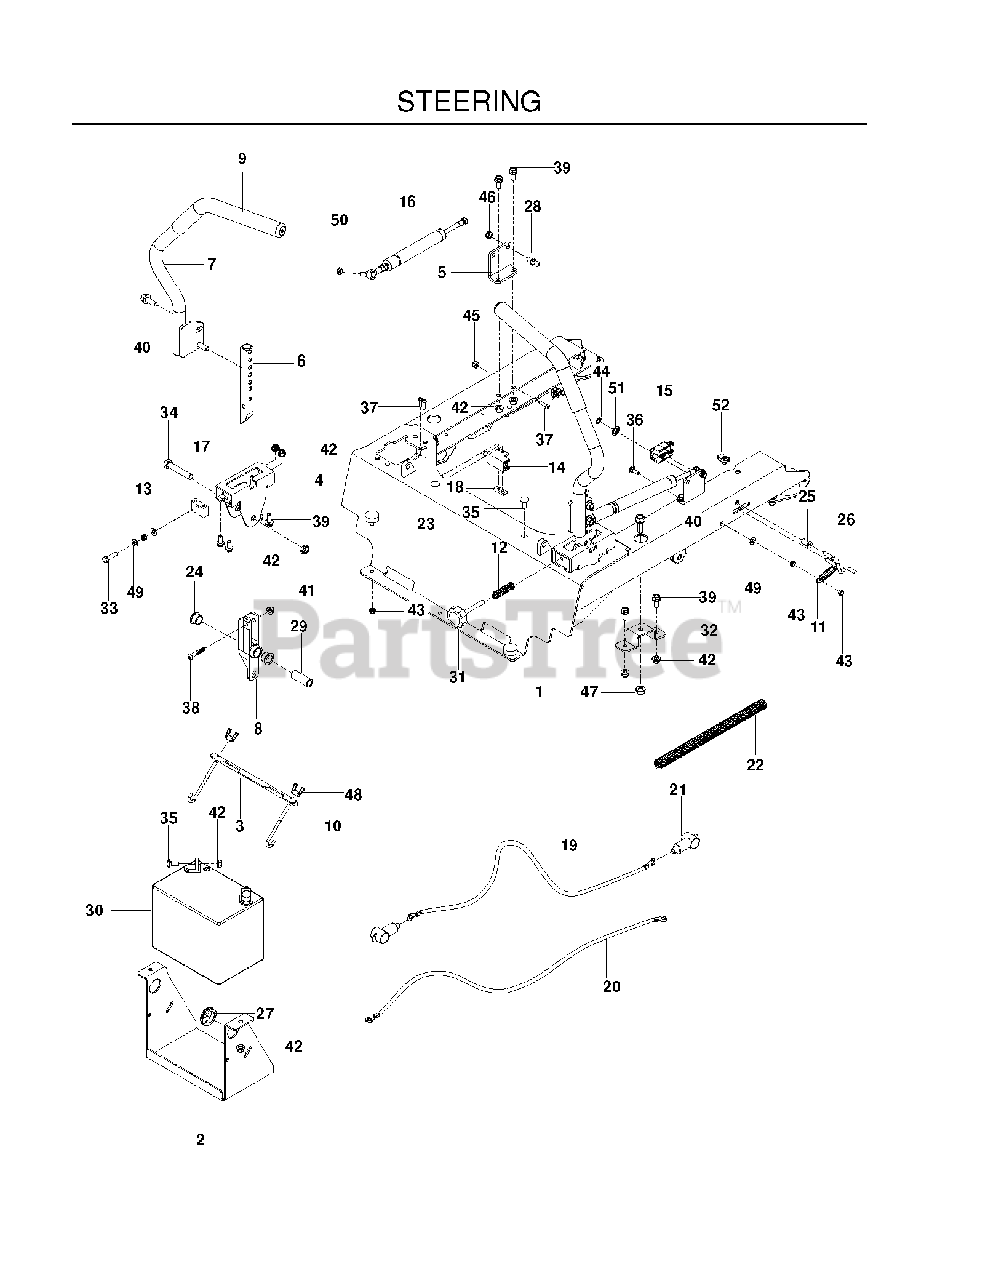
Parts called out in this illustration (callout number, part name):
1	FRAME SEAT MOUNT ORANGE
2	BRACKET, BATTERY, BLK
3	BRACKET, BATTERY MOUNT
4	BRACKET, CONTROL
5	BRACKET.DAMPNER
6	LEVER, MOTION
7	LEVER.WITH GRIP.RT
8	LEVER.CONTROL.SHORT
9	GRIP - DRIVE LEVER 12"
11	SPRING, EXTENSION
12	SPRING COMPRESSION 2.0
14	SWITCH, INTERLOCK
15	SWITCH, BRAKE 3P
16	ASSEMBLY, DAMPENER
17	BLOCK.TRACKING
18	BLOCK, LOWER
19	CABLE, POSITIVE, 55"
20	CABLE, NEG, 55"
22	LOOM, SPLIT, CONVOLUTED
23	BUMPER, 1/4-20 STUD, 1/4
24	BEARING, FLANGE
25	BUSHING, 1/4 FLANGE
26	LINK, SWITCH
27	RUBBER GROMMET
28	STUD.BALL.10MM
29	SPACER, PIVOT CONTROL
30	BATTERY, 12 V 330 AMP
32	MOUNT, MID-SECTION, BLK
33	BOLT, TAP 5/16-18
34	HCS 1/2C X 2 3/4
35	BOLT 5/16C X 3/4" CARRIAGE
36	RHSNB 1/4C X 3/4
37	SCR #10-24 X .75 SKT HD BLK
38	SCREW 5/16-18 X 1 3/4 BTN-HD
39	HHFS 5/16-18 X 3/4
40	HHFS 3/8-16 X 1 GRD 5 ZD
41	NUT 1/2-13 HEX JM NYL
42	5/16-18 NYLOC FLANGE NUT
43	JAM NUT 1/4C (2 2 PW01)
45	NUT 10-24 NYLOC
46	NUT 5/16 NYLOC
47	NUT 3/8-16 HEX FLG NYLOC ZD
48	WING NUT 1/4
49	FLAT WASHER 5/16 SAE
50	WASHER 5/16 LOCK
51	NUT 3/8 PALNUT RTNG BLK PHOS
52	U-CLIP 5/16-18 NUT RETAINER
